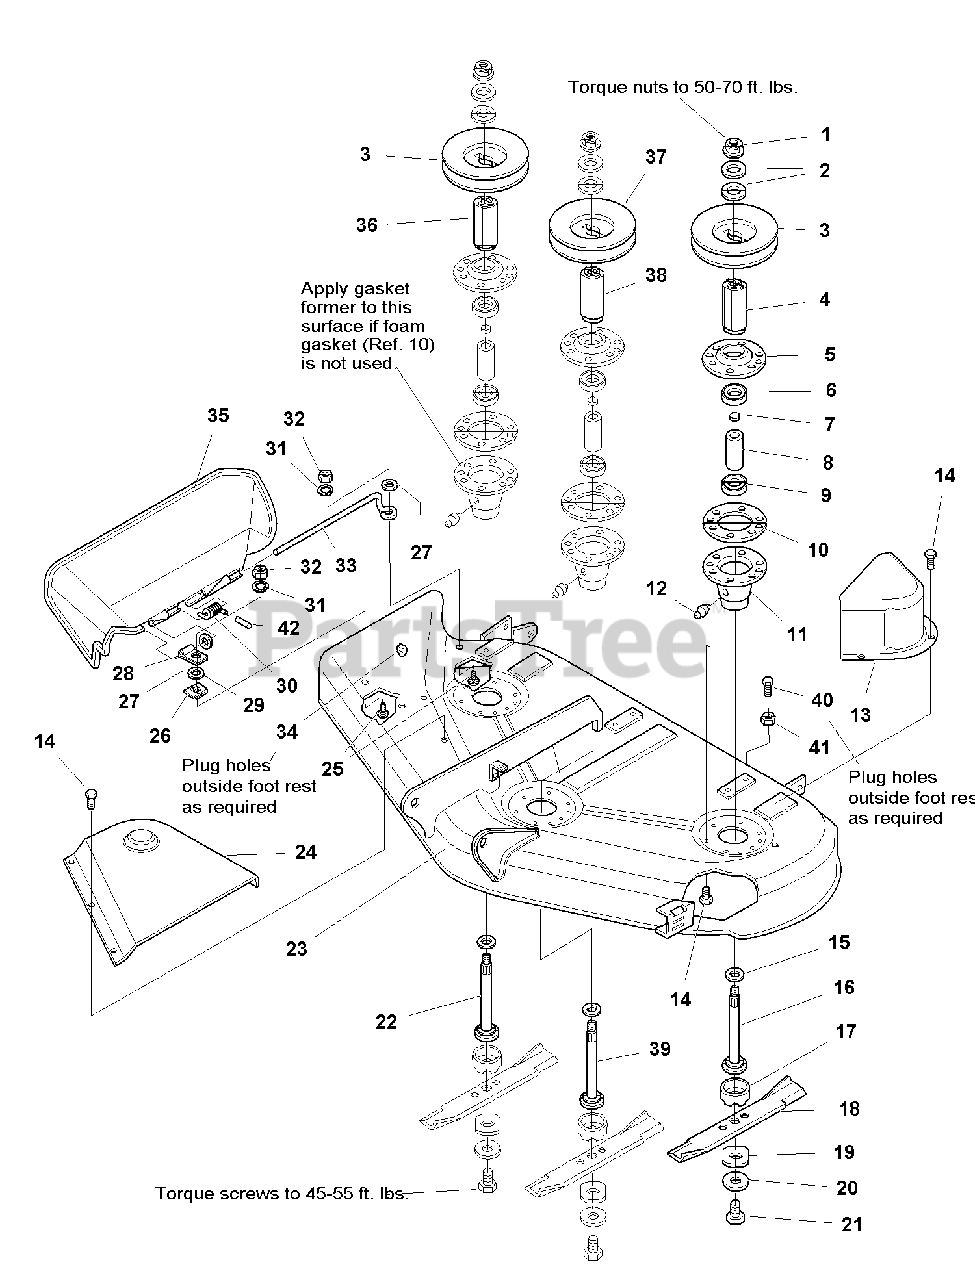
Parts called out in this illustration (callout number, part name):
1	NUT, Hex, Flange, 9/16-8
2	WASHER, Belleville
3	PULLEY, RH Arbor & LH Arbor, 41/2
4	HUB, Adapter, LH
5	COVER, Arbor Housing
6	BEARING, Upper
7	SPACER, Sleeve, Upper Bearing
8	SPACER, Arbor, Internal
9	BEARING, Lower
10	GASKET, Foam
11	HOUSING ASSEMBLY, Arbor Bottom, w/Lube Fitting
12	FITTING, Grease
13	COVER, Arbor LH
14	CAPSCREW, Taptite Hex Washer Head, 5/16-18 x 3/4
15	WASHER, Cup, 23/32
16	SHAFT, Arbor LH
17	SHIELD, Grass, Lower
18	BLADE, Mower, 16-1/8
19	WASHER, Hex
20	WASHER, Spring
21	CAPSCREW, Hex, Head, 7/16-14 x 1-1/4
22	SHAFT, Arbor (RH)
23	HOUSING ASSEMBLY, Red
23	HOUSING ASSEMBLY, Orange
23	HOUSING ASSEMBLY, Black
24	COVER, Arbor (RH)
25	CARRIAGE BOLT, 1/4-20 x 7/8
26	NUT, Push
27	WASHER, Plain, 1/4
29	WASHER, Plain, 5/16
30	SPRING, Deflector Retaining
32	NUT, Hex, 1/4-20 ESNA
33	ROD, Deflector, Front
34	* PLUG, Hole
35	DEFLECTOR, Plastic
36	HUB, Pulley, RH
37	PULLEY, Arbor (Center)
38	HUB, Pulley (Center)
39	SHAFT, Arbor (Center)
40	* CAPSCERW, Hex Head, Taptite, 5/16-18 x 1/2
41	* NUT, Hex Whiz Lock, 5/16-18
42	CAP, Spring End
